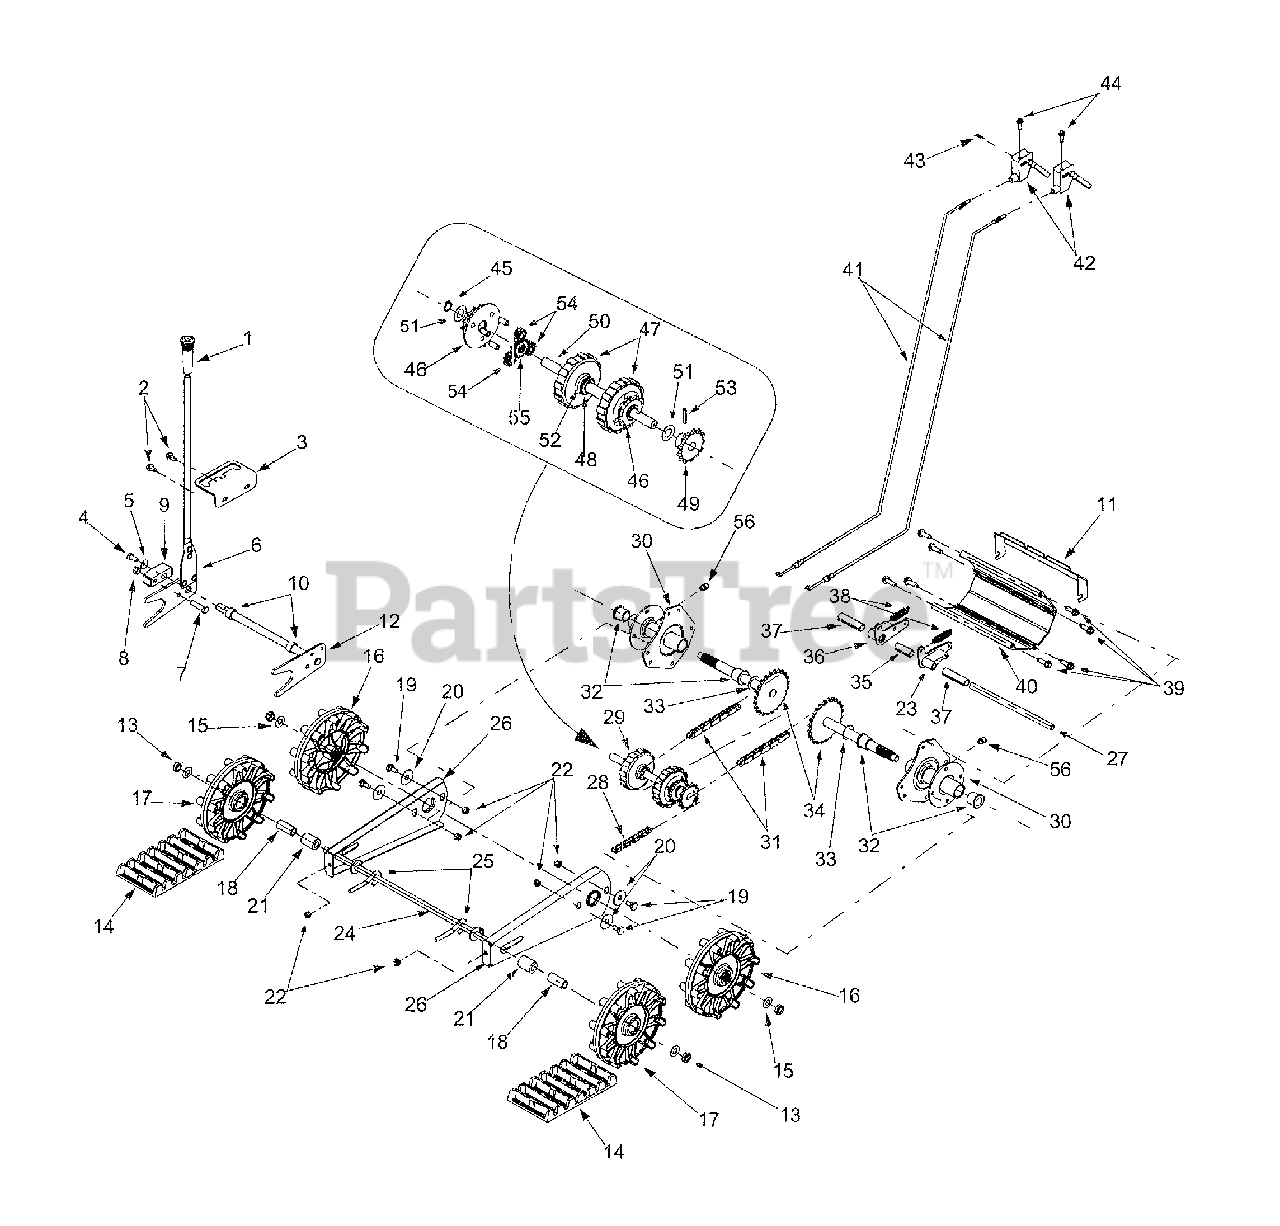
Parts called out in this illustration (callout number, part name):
2	Tap Screw, 5/16-18 x .625
4	Hex Cap Screw, 5/16-24 x .75
5	Bell Washer, .34 ID x .872 OD
7	Hex Cap Screw, 3/8-24 x 1.5
8	Hex Nut, 3/8-24
9	Lift Shaft Drive
10	Spacer, .628 ID x .875 OD x.5
13	Jam Nut, 1/2-20
14	Snow Track
15	Flat Washer, .5 x 1 x .06
16	Track Drive Wheel
17	Track Idler Wheel
18	Spacer, .51 ID x .75 OD x 1.67
19	Screw, .435 x .178-5/16 x .56
20	Flat Washer, .442 x 1.38 x .06
21	Spacer, .51 ID x 1 OD x 1.34
22	Hex Nut, 5/16-18
23	LH Dogg Assembly
24	Idler Axle Assembly
25	Eye Bolt, 5/16-18 x 3
27	Actuator Shaft
28	Chain
29	Track/Steering Shaft Assy
30	Track Hub Assy w/Fitting
31	Chain
32	Flange Bearing
33	Flat Washer, .793 x 1.24 x .06
34	Axle Assembly
35	Spacer, .514 x .630 x 1.59
36	RH Dogg Assembly
37	Spacer, .514 x .630 x 2.44
38	Extension Spring
39	Tap Screw, 5/16-18 x 1
40	Track Housing
41	Steering Cable
42	Steering Trigger
43	Flange Nut
44	Screw, #10-24 x 1.375
45	Retaining Ring
46	Carrier Assembly
47	Ring Gear
48	Retaining Ring
49	13-Tooth Sprocket
50	Track Steering Drive Shaft
51	Flat Washer, .58 x 1.06 x .02
52	Flat Washer, 5/8 x 1 x .03
53	Spiral Pin, 3/16 x 1
54	12-Tooth Gear
55	18-Tooth Gear
56	Grease Fitting, 3/16" Drive
